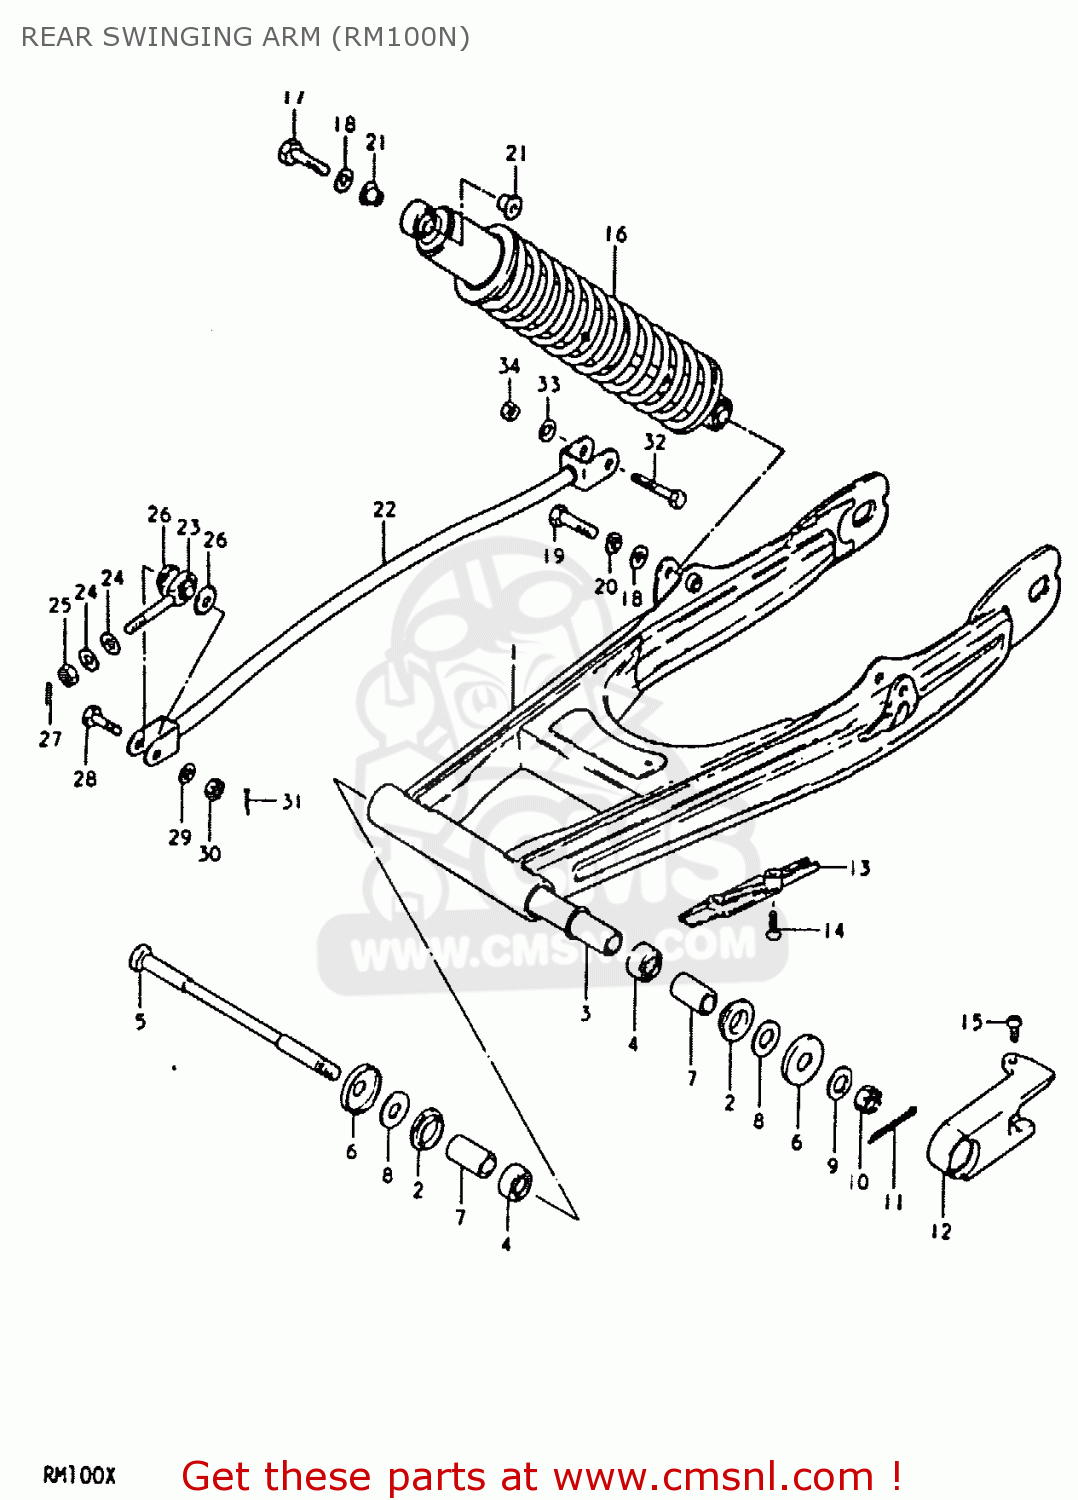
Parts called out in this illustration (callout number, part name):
1	SWING ARM ASSEMBLY,REAR
2	BUSH,RR SWINGINGARM PIVOT
3	SPACER,SWING ARM,CENTER
4	ROLLER BEARING (17X24X2
5	SHAFT,RR SWINGINGARM PIVOT
6	COVER,REAR SWING ARM DUST
7	SPACER,RR SWGARM PIVOT
8	WASHER
9	WASHER
10	NUT, REAR AXLE
11	COTTER PIN
12	BUFFER,CHAIN TOUCH DEFLECTOR
13	BUFFER,CHAIN TOUCH DEFLECTOR
14	SCREW
15	SCREW
16	ABSORBER ASSEMBLY,REAR SHOCK
17	BOLT
18	WASHER
19	BOLT 10X40
20	LOCK WASHER
21	SPACER,RR SHK ABS INNER
22	TORQUE LINK,REAR
23	BEARING
24	WASHER
25	NUT
26	DUST SEAL,TORQUE LINK FR BRG
27	PIN
28	BOLT 8X28
29	WASHER
30	NUT 8MM
31	PIN 20X20
32	BOLT 10X40
33	WASHER
34	NUT
